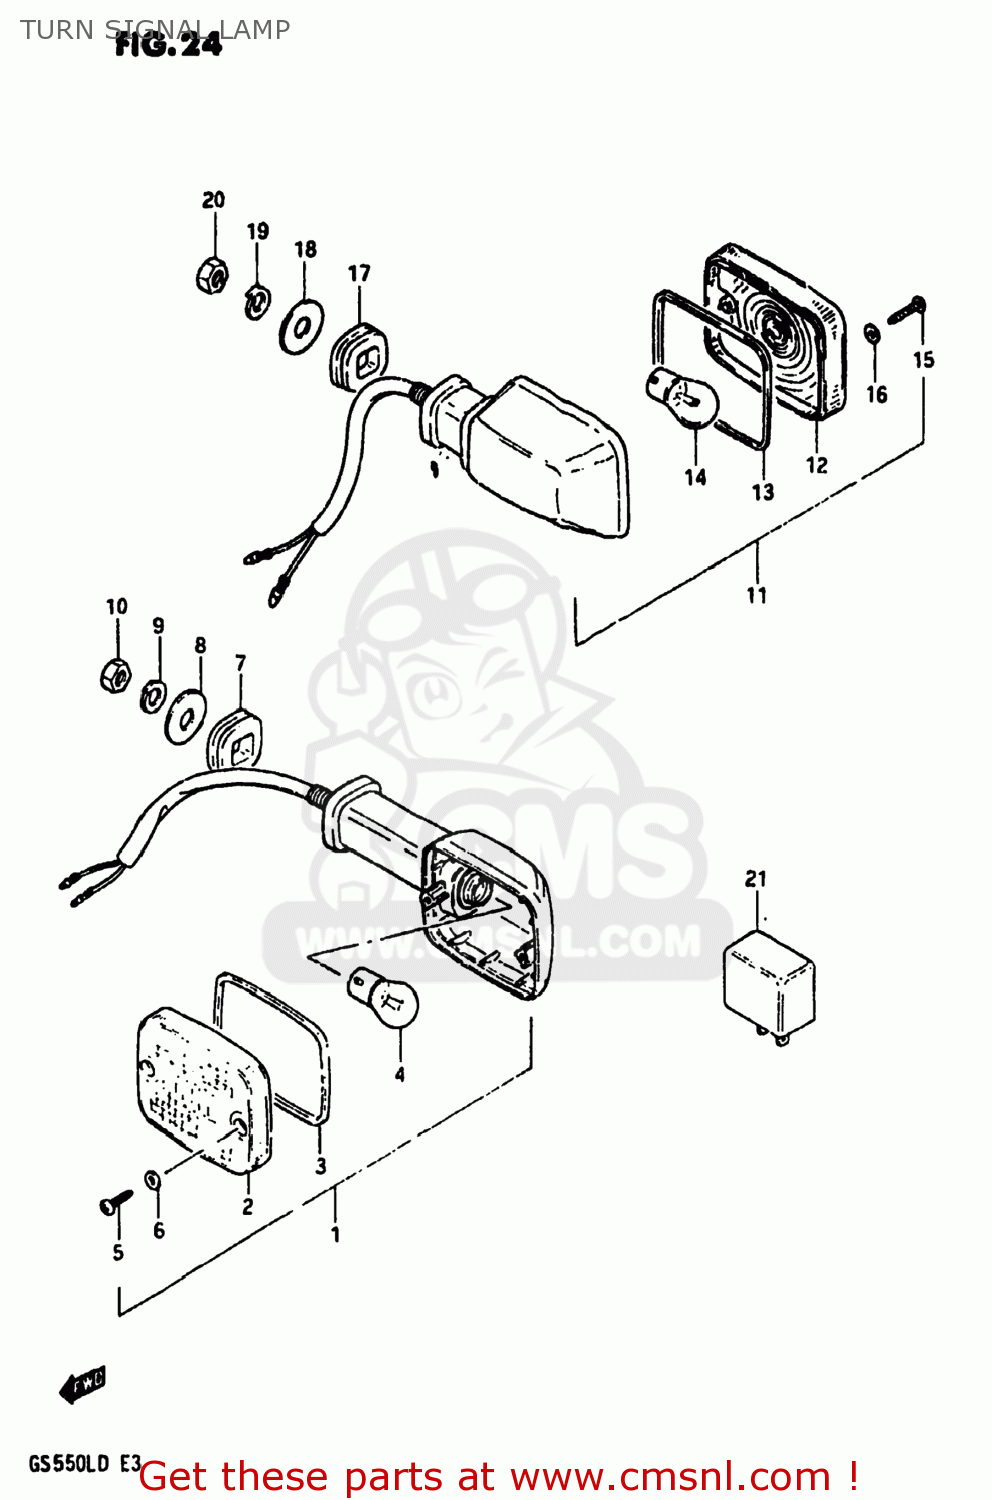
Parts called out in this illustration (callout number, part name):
1	LAMP ASSEMBLY,FRONT TURN SIGNAL
2	LENS
3	GASKET (NAS)
4	BULB(12V23W,STANLEY,A4577A)
5	SCREW
6	GASKET (NAS)
7	CUSHION
8	WASHER (10.5X30X2.3)
9	LOCK WASHER
10	NUT
11	LAMP ASSEMBLY,REAR TURN SIGNAL
12	LENS
13	GASKET (NAS)
14	BULB(12V23W,STANLEY,A4577A)
15	SCREW
16	GASKET (NAS)
17	CUSHION
18	WASHER (10.5X30X2.3)
19	LOCK WASHER
20	NUT
21	RELAY,TURN SIGNAL
